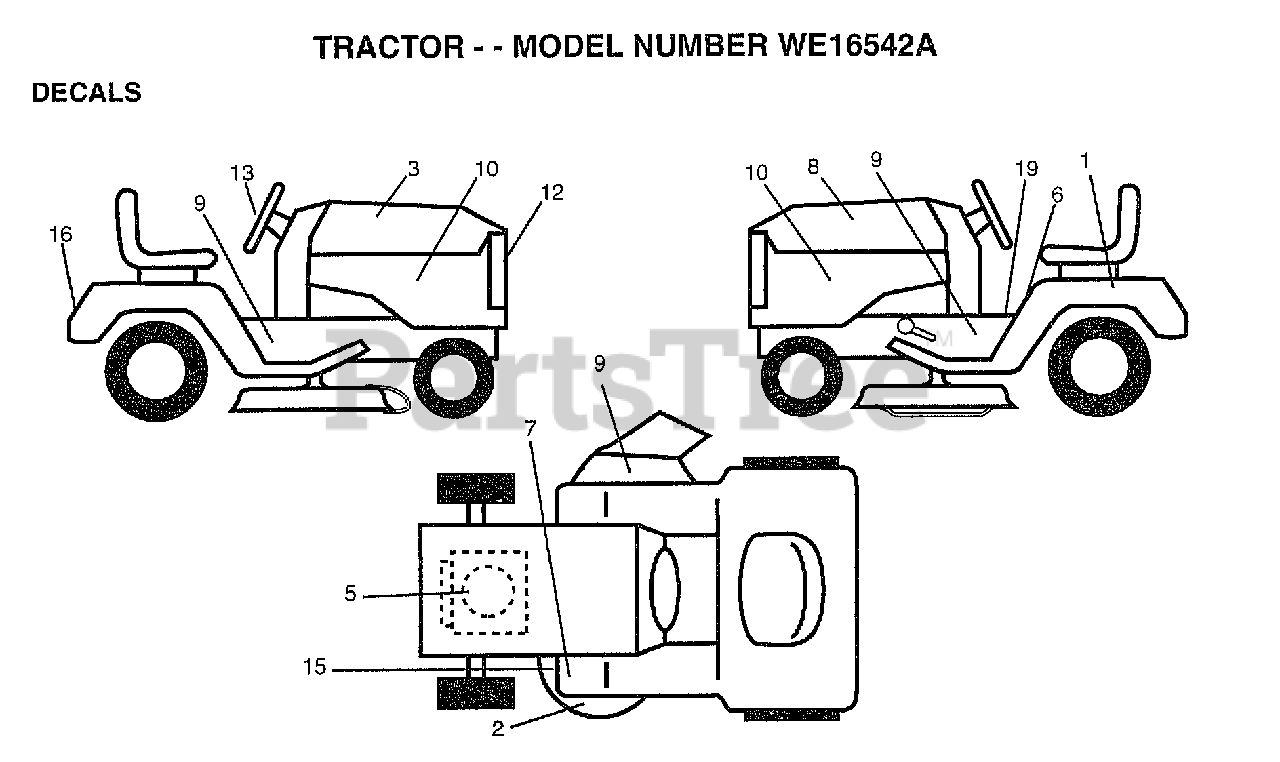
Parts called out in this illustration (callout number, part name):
1	DECAL.BATRY.3-3908
2	DECAL, DECK GRASSEATER
3	DECAL.HOOD.RH.
5	DECAL ENGINE
6	DECAL.CAUT.ENG/FR
7	DECAL.CLUTCH/BRK
8	DECAL.HOOD.LH
9	"DECAL, WARNING"
10	DECAL PNL SIDE
12	DECAL, GRILLE LENS
13	DECAL, INS STRG WH
15	"DECAL-SCHEM,BELT"
16	DECAL.FENDER.LOGO
19	"DECAL.OPER,SDL"
